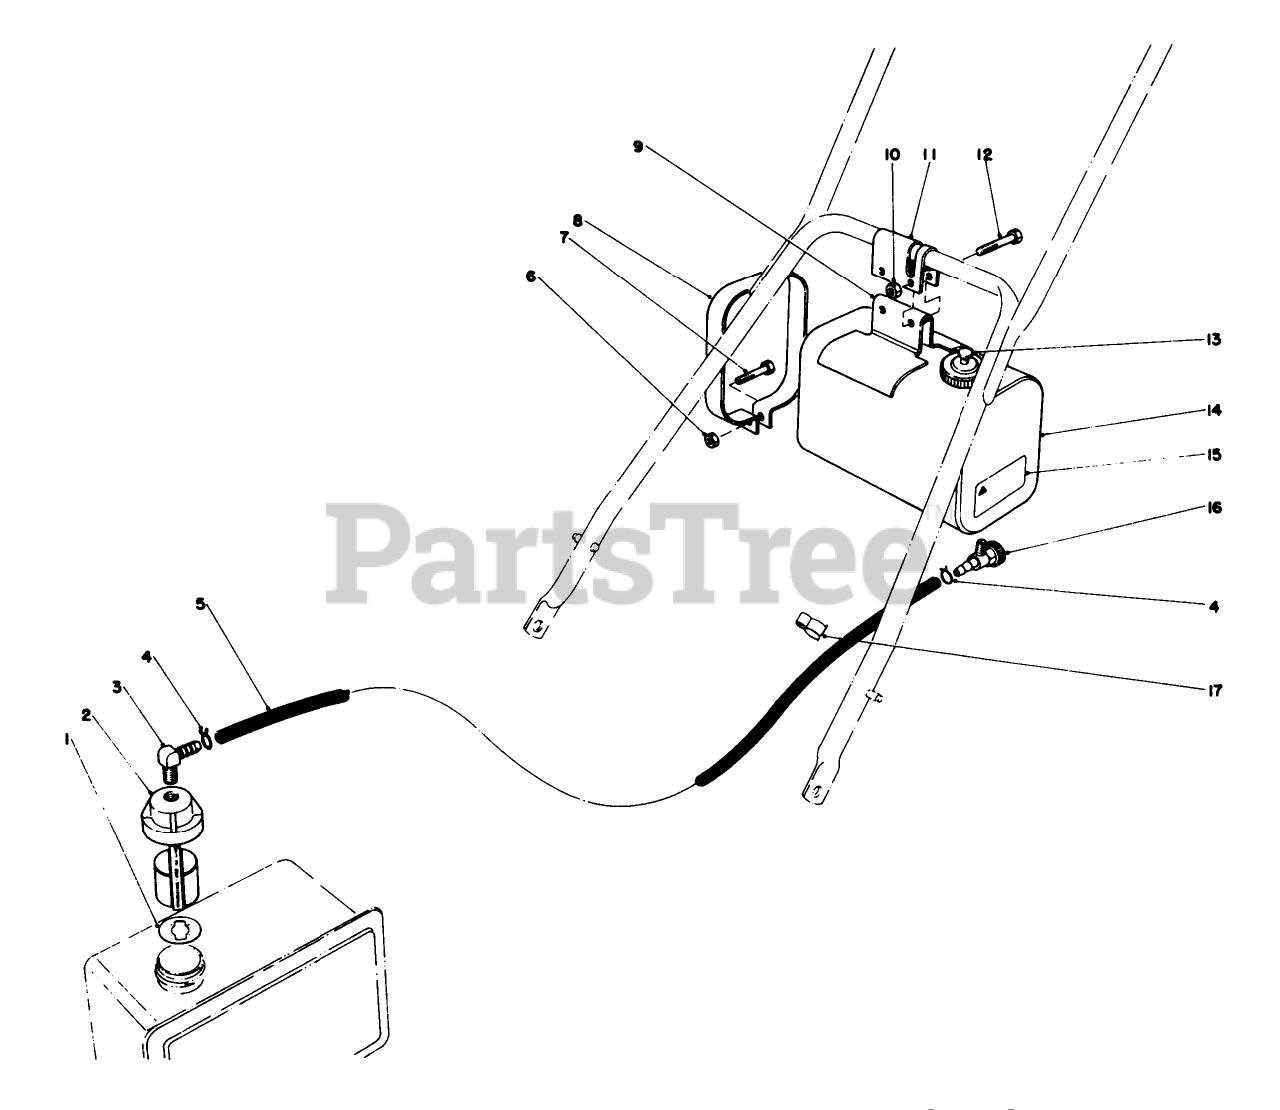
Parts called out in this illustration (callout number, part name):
2	FUEL CONT VALVE ASM
3	CONNECTOR-HOSE
7	SCREW-HH
12	SCREW-HH
